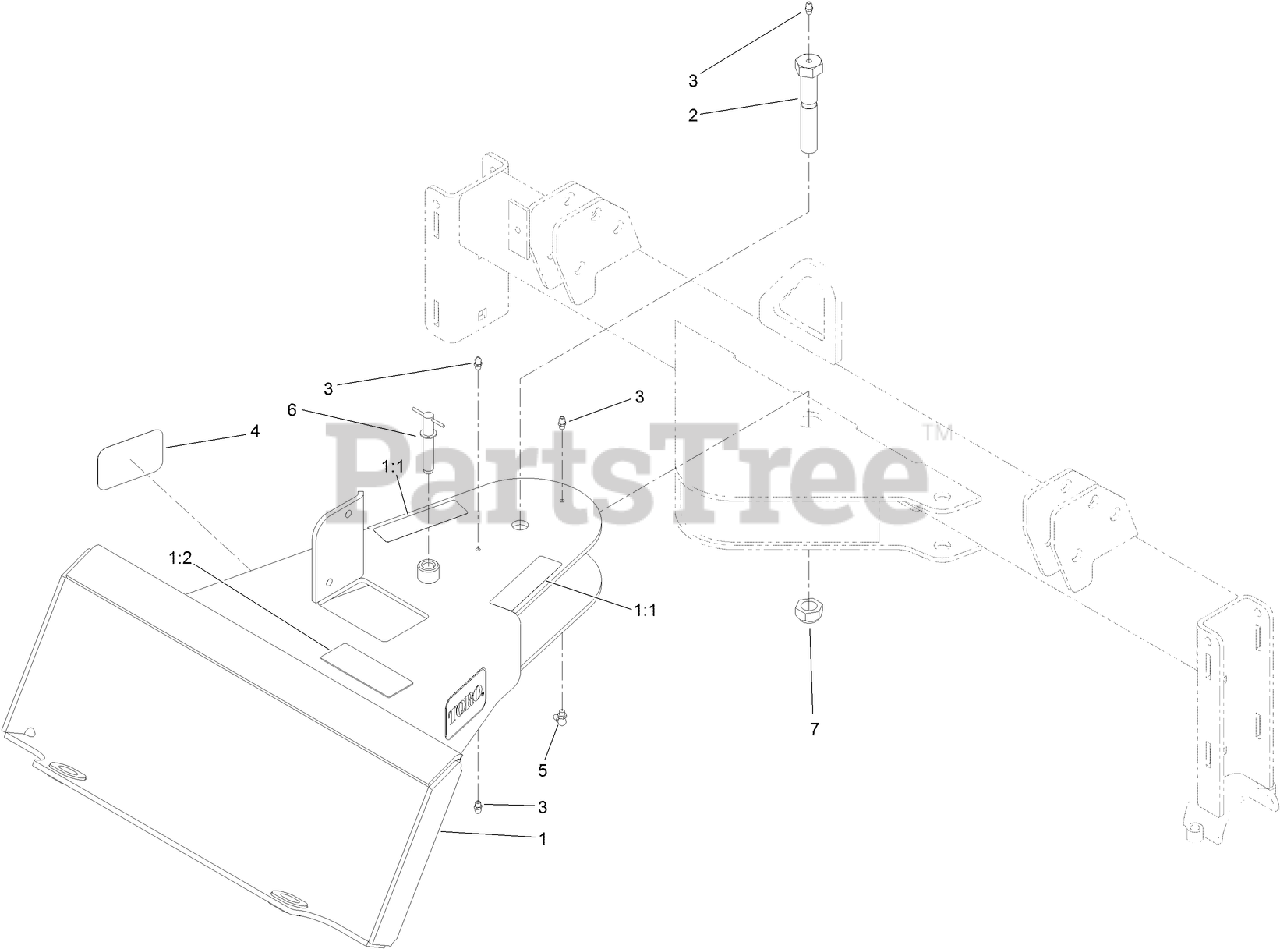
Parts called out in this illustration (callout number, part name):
1	ATTACHMENT MOUNT ASM
1:1	DECAL-WARNING
1:2	DECAL-WARNING
2	BOLT-PIVOT
3	FITTING-GREASE
4	DECAL
5	FITTING-GREASE
6	PIN-SHOULDER, T-HANDLE
7	LOCKNUT-STOVER
